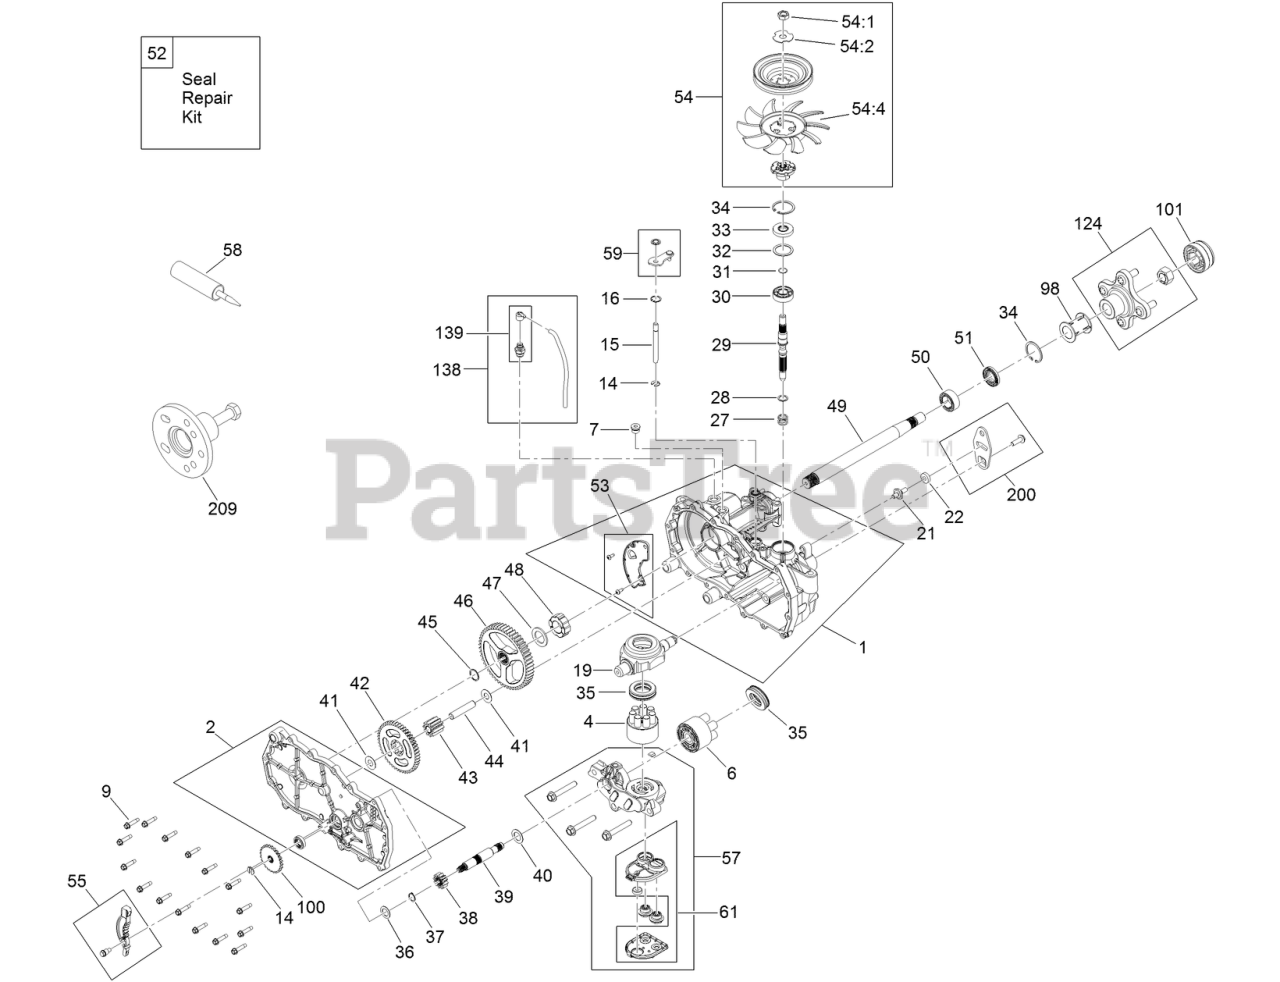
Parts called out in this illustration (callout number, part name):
1	MAIN HOUSING ASM
2	SIDE ASM
4	PUMP BLOCK ASM
6	CYLINDER BLOCK KIT
7	PLUG-THREAD, STRAIGHT
9	SCREW-HHF
14	RING-RETAINING, EXTERNAL
15	ROD-BYPASS
16	RING-RETAINING, INTERNAL
19	SWASHPLATE-TRUNNION
22	PUCK-FRICTION
27	SPRING-BLOCK
28	WASHER
29	SHAFT-INPUT
30	BEARING-BALL
31	RING-RETAINING
32	SPACER
33	SEAL-LIP
34	RING-RETAINING
35	BEARING-THRUST
36	WASHER-FLAT
37	RING-RETAINING
38	GEAR-PINNION, 13T
39	SHAFT-MOTOR
40	WASHER
41	WASHER
42	GEAR-10T/48T
43	GEAR-JACKSHAFT, 10T
44	PIN-JACKSHAFT
45	RING-SPIRAL, RETAINING
46	GEAR-52T, BULL
47	WASHER
48	BEARING-SLEEVE
49	SHAFT-AXLE
50	BUSHING-AXLE
51	SEAL-LIP
52	SEAL KIT
53	EXPANSION PLATE KIT
54	FAN AND PULLEY KIT
54:1	NUT-HJ
54:2	WASHER-SLOTTED
54:4	FAN 7.0 X 10 BLADE
55	BRAKE ARM KIT
57	CENTER SECTION FILTER KIT
58	SEALANT
59	BYPASS ARM KIT
61	FILTER KIT
98	TUBE-AXLE
100	DISC-BRAKE, COG
101	COVER-NUT, AXLE
124	HUB KIT
138	BREATHER KIT
139	BREATHER ASM
200	CONTROL ARM KIT
